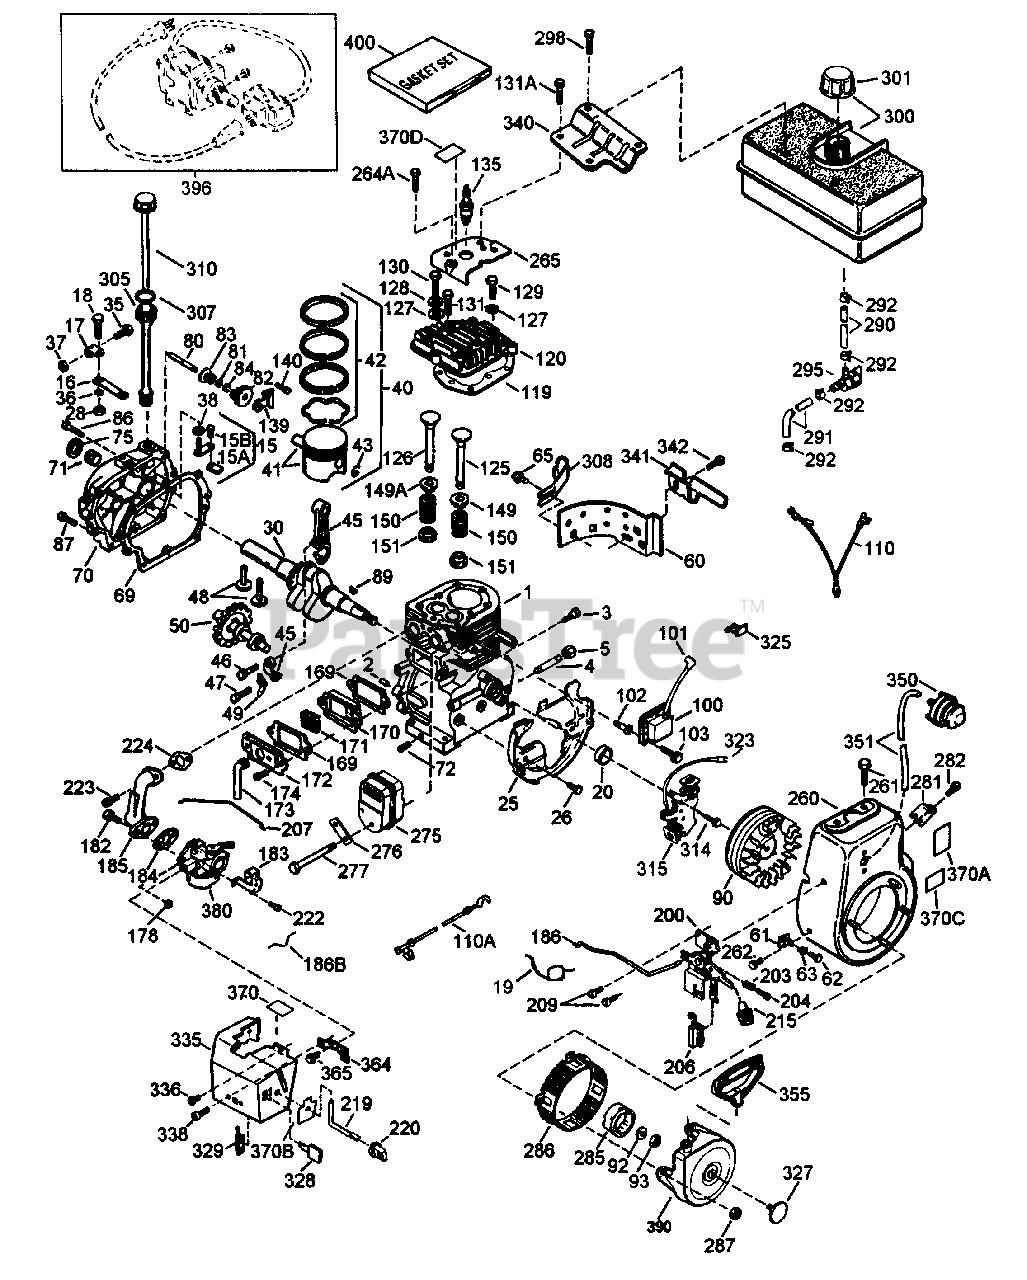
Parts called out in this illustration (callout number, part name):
1	Cylinder
3	Screw, 1/4-20 x 1/2"
4	Oil Drain Extension
5	Extension Cap
15	Governor Rod
15A	Governor Yoke
15B	Screw, 6-40 x 5/16"
16	Governor Lever
17	Governor Lever Clamp
18	Screw, 8-32 x 5/16"
19	Speed Control Spring
25	Blower Housing Baffle
26	Screw, 1/4-20 x 5/8"
28	Lock Nut, 8-32
30	Crankshaft
35	Screw, 10-32 x 3/4"
36	Lock Washer
37	Lock Nut, 10-32
38	Retaining Ring
40	Piston, Pin & Ring Set (Std.)
41	Piston & Pin Ass'y. (Std.)
42	Ring Set (Std.)
43	Piston Pin Retaining Ring
45	Connecting Rod Ass'y.
46	Connecting Rod Bolt
47	Connecting Rod Bolt
48	Valve Lifter
49	Oil Dipper
50	Camshaft (MCR)
60	Blower Housing Extension
61	Grommet Mounting Bracket
62	Screw, 8-32 x 3/8"
65	Screw, 10-24 x 1/2"
69	Cylinder Cover Gasket
70	Cylinder Cover
71	Crankshaft Bushing
72	Oil Drain Plug
80	Governor Shaft
82	Governor Gear Ass'y.
83	Governor Spool
84	Retaining Ring
86	Screw, 1/4-20 x 1-3/16"
87	Screw, 1/4-20 x 1-11/16"
89	Flywheel Key
90	Flywheel (w/Ring Gear)
92	Lock Washer
93	Flywheel Nut
100	Solid State Ignition
101	Spark Plug Cover
102	Solid State Mounting Screw
103	Screw, Torx T-15, 10-24 x 15/16"
110	Ground Wire
110A	Ground Wire
119	Cylinder Head Gasket
120	Cylinder Head
125	Exhaust Valve (Std.)
126	Intake Valve (Std.)
128	Belleville Washer
129	Screw, 5/16-18 x 1-3/4"
130	Screw, 5/16-18 x 1-1/2"
131	Screw, 5/16-18 x 2"
131A	Screw, 5/16-18 x 5/8"
135	Resistor Spark Plug
139	Governor Gear Bracket
140	Screw, 10-24 x 1/2"
149	Valve Spring Cap
149A	Valve Spring Cap
150	Valve Spring
151	Valve Spring Keeper
169	Valve Cover Gasket
170	Breather Body
171	Breather Element
172	Valve Cover
173	Breather Tube
174	Screw, 10-24 x 1/2"
178	Nut & Lock Washer, 1/4-28
182	Screw, 1/4-28 x 1"
183	Choke Bracket
184	Carburetor
185	Intake Pipe
186	Governor Link
186B	Choke Spring
200	Control Bracket
203	Compression Spring
204	Screw, 5-40 x 7/16"
209	Screw, 10-32 x 1/2"
215	Control Knob
219	Choke Rod
220	Control Knob
222	Screw, 10-32 x 1/2"
223	Screw, Torx T-30, 5/16-18 x 1-1/8"
224	Intake Pipe Gasket
260	Blower Housing
261	Screw, 5/16-18 x 3/4"
262	Screw, Torx T-40, 5/16-24 x 21/32"
264A	Screw, 1/4-20 x 5/8"
265	Cylinder Head Cover
276	Locking Plate
277	Screw, 5/16-18 x 4-3/16"
281	Starter Bubble Cover
282	Screw, 8-32 x 3/8"
285	Starter Cup
286	Starter Screen
287	Nut & Lock Washer, 1/4-28
290	Fuel Line
291	Fuel Line
292	Fuel Line Clamp
295	Fuel Shut-Off Valve
298	Screw, 1/4-15 x 3/4"
300	Fuel Tank
301	Fuel Cap
305	Oil Fill Tube
308	Fill Tube Clip
314	Screw, 1/4-20 x 3/4"
315	Alternator Coil (18 Watt)
325	Wire Clip
327	Starter Plug
328	Ignition Key
335	Carburetor Cover
336	Screw, 10-32 x 1/2"
338	Screw, 10-32 x 3/8"
340	Fuel Tank Bracket
341	Fuel Tank Bracket
342	Screw, 1/4-20 x 5/8"
350	Primer Ass'y.
351	Primer Line
355	Starter Handle
364	Carburetor Cover Bracket
365	Screw, 8-32 x 27/64"
370	Warning Decal
370A	Lubricant on Decal
370B	Choke Decal
370C	Primer Decal
370D	Lubrication Decal
380	Carburetor
390	Rewind Starter
396	Electric Starter Motor
400	Gasket Set
